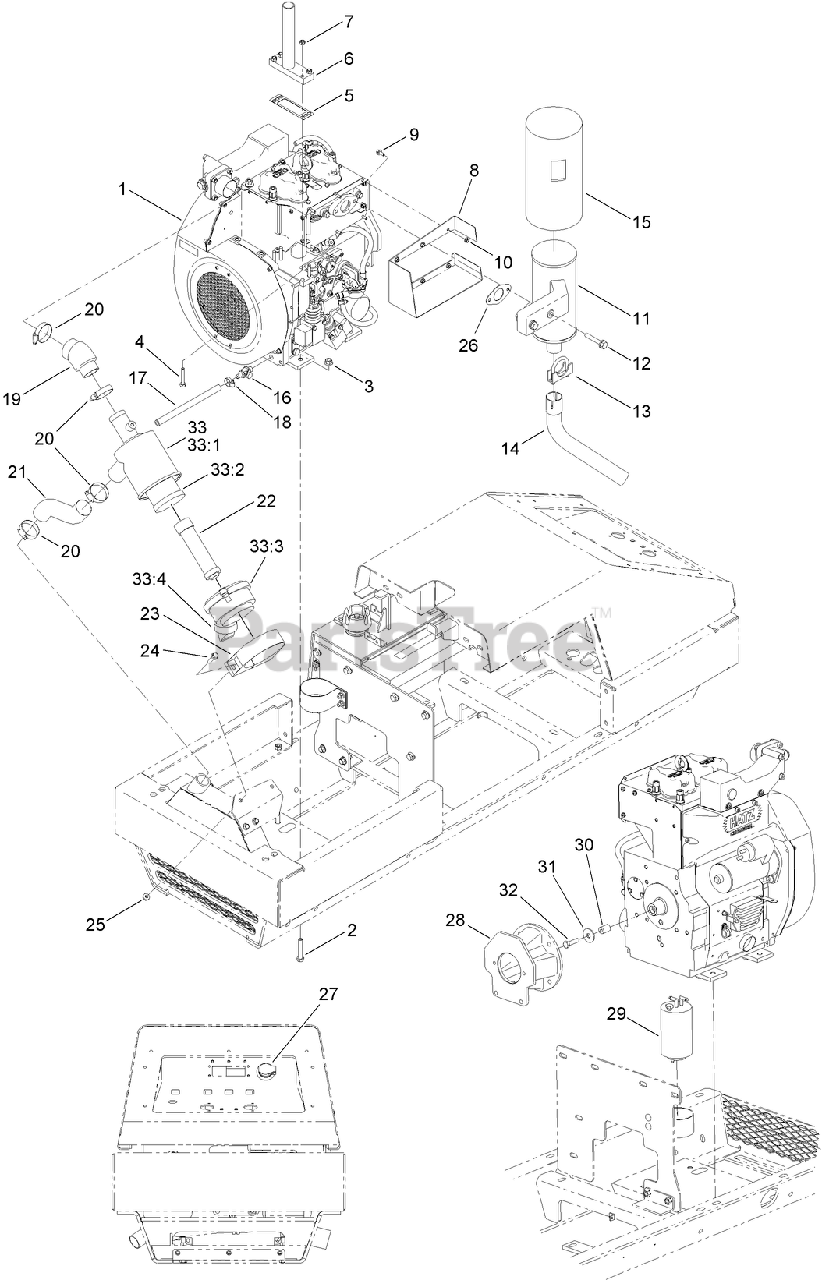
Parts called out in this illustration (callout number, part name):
1	ENGINE ASM
2	SCREW-HH
3	NUT-HF
4	Screw-HH
5	GASKET-FILLER, OIL
6	FILLER-OIL
7	NUT-LOCK, NI
8	DUCTING-AIR, OUT EXTENSION
9	SCREW-HHF
10	NUT-HF
11	MUFFLER
12	SCREW-HHF
13	CLAMP-MUFFLER
14	TAILPIPE
15	BLANKET-INSULATION, EXHAUST
16	VALVE-DRAIN, OIL
18	CLAMP-HOSE
19	HOSE-INTAKE, AIR, ENGINE
20	CLAMP-HOSE
21	HOSE-FLEX, VACUUM
22	FILTER-SAFETY
23	BAND-MOUNTING, AIR CLEANER
24	SCREW-HHF
25	NUT-HF
26	GASKET
27	SWITCH-IGNITION
28	HOUSING-MOUNTING, PUMP
29	FILTER-FUEL/WATER SEPARATOR
30	INSERT-THREAD
31	WASHER-FLAT
32	SCREW-HH
33	AIR CLEANER ASM
33:1	COVER-AIR CLEANER
33:2	ELEMENT-FILTER, AIR
33:3	COVER-LATCHING
33:4	VALVE-VACUATOR
